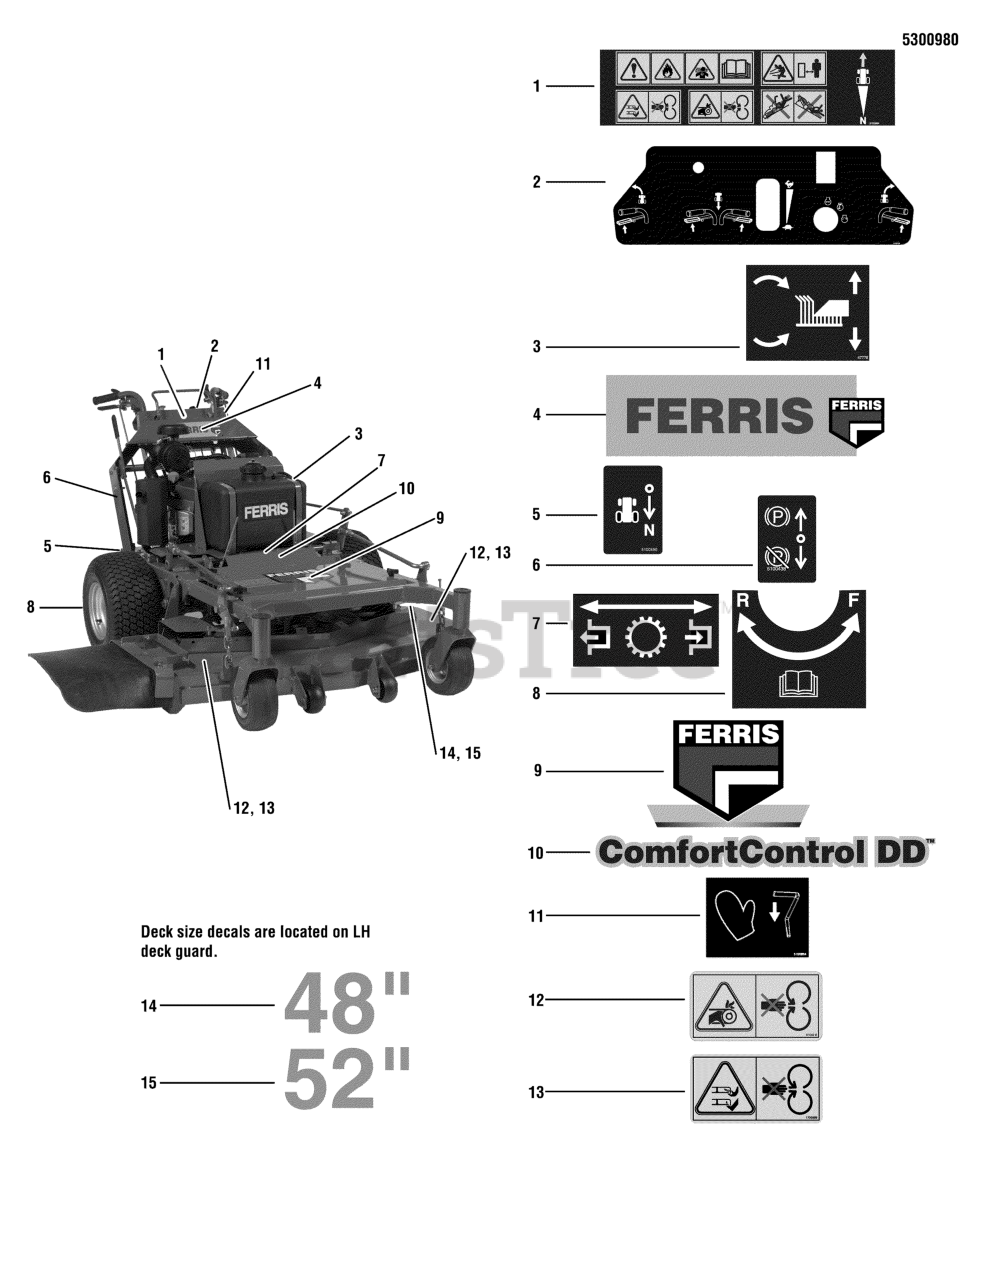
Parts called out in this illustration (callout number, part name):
1	DECAL, WARNING
3	DECAL, CUT HEIGHT ADJUSTMENT
4	DECAL, FERRIS TEXT & LOGO
5	DECAL, PEDAL
6	DECAL, PARKING BRAKE
7	DECAL, HYDRO RELEASE
8	DECAL, FORWARD / REVERSE
9	DECAL, FERRIS BADGE
10	DECAL, COMFORT CONTROL
11	DECAL, AUXILARY OPC
12	DECAL, CE DANGER
13	DECAL-DANGER ROTATING BLADE SYMBOLS
14	DECAL, 48
15	DECAL, 52
